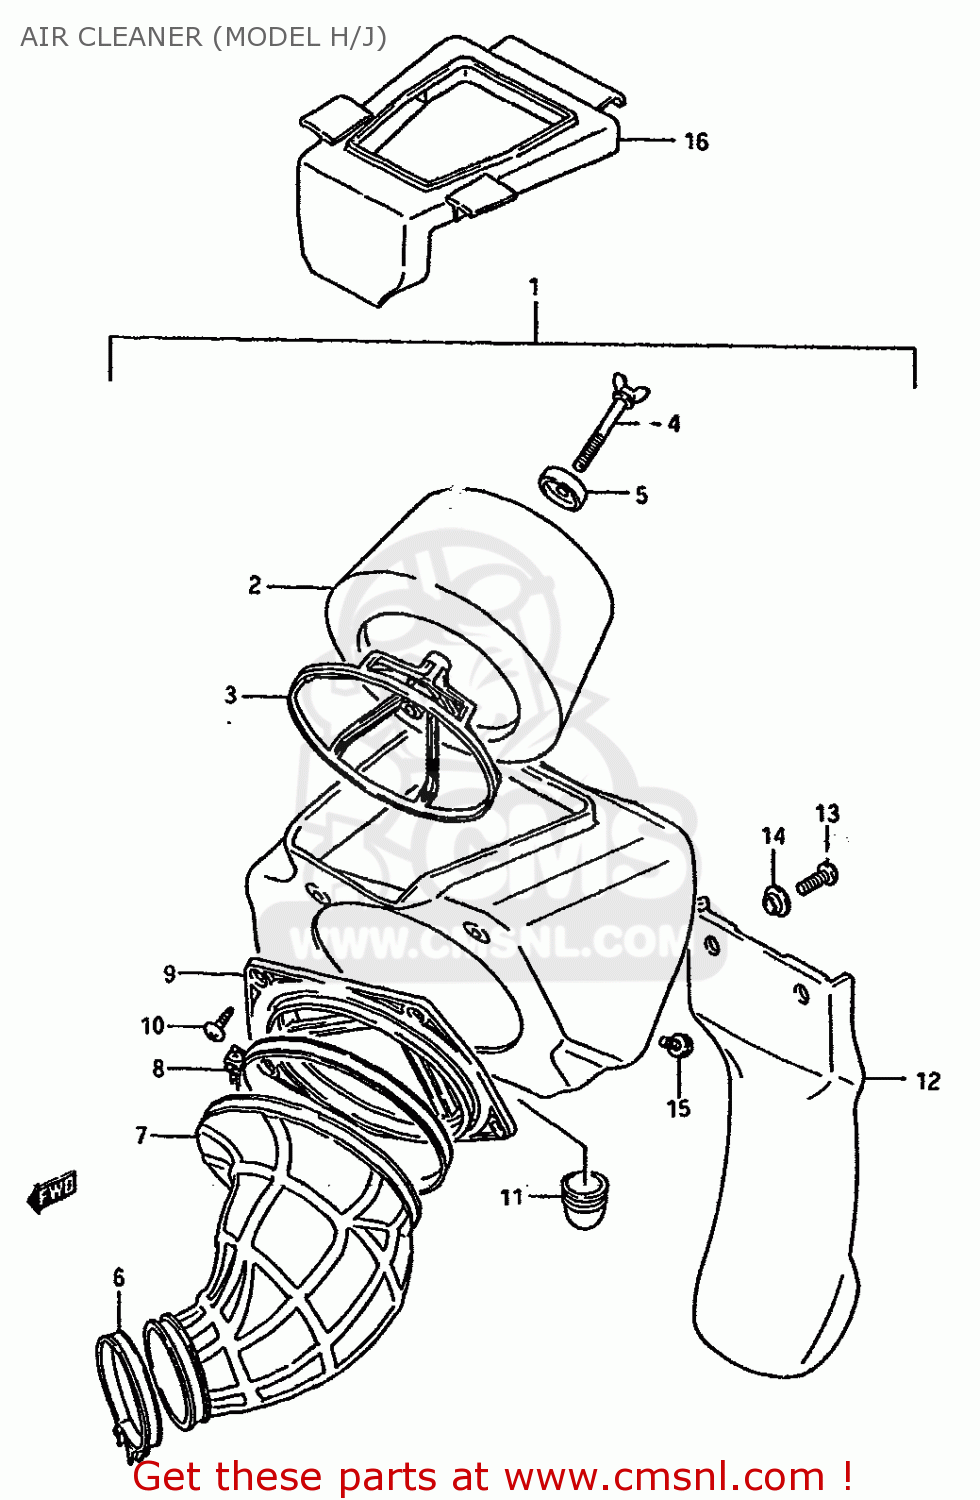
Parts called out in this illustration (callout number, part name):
1	CLEANER ASSEMBLY,AIR
2	FILTER,AIR CLEANER
3	HOLDER,FILTER
4	BOLT,WING
5	WASHER,AIR CLEANER
6	CLAMP
7	TUBE,AIR CLEANER OUTLET
8	CLAMP
9	HOLDER,FILTER
10	SCREW
11	HOSE,AIR CLEANER DRAIN
12	GUARD,MUD
13	SCREW
14	COLLAR
15	BOLT
16	GUARD,MUD
